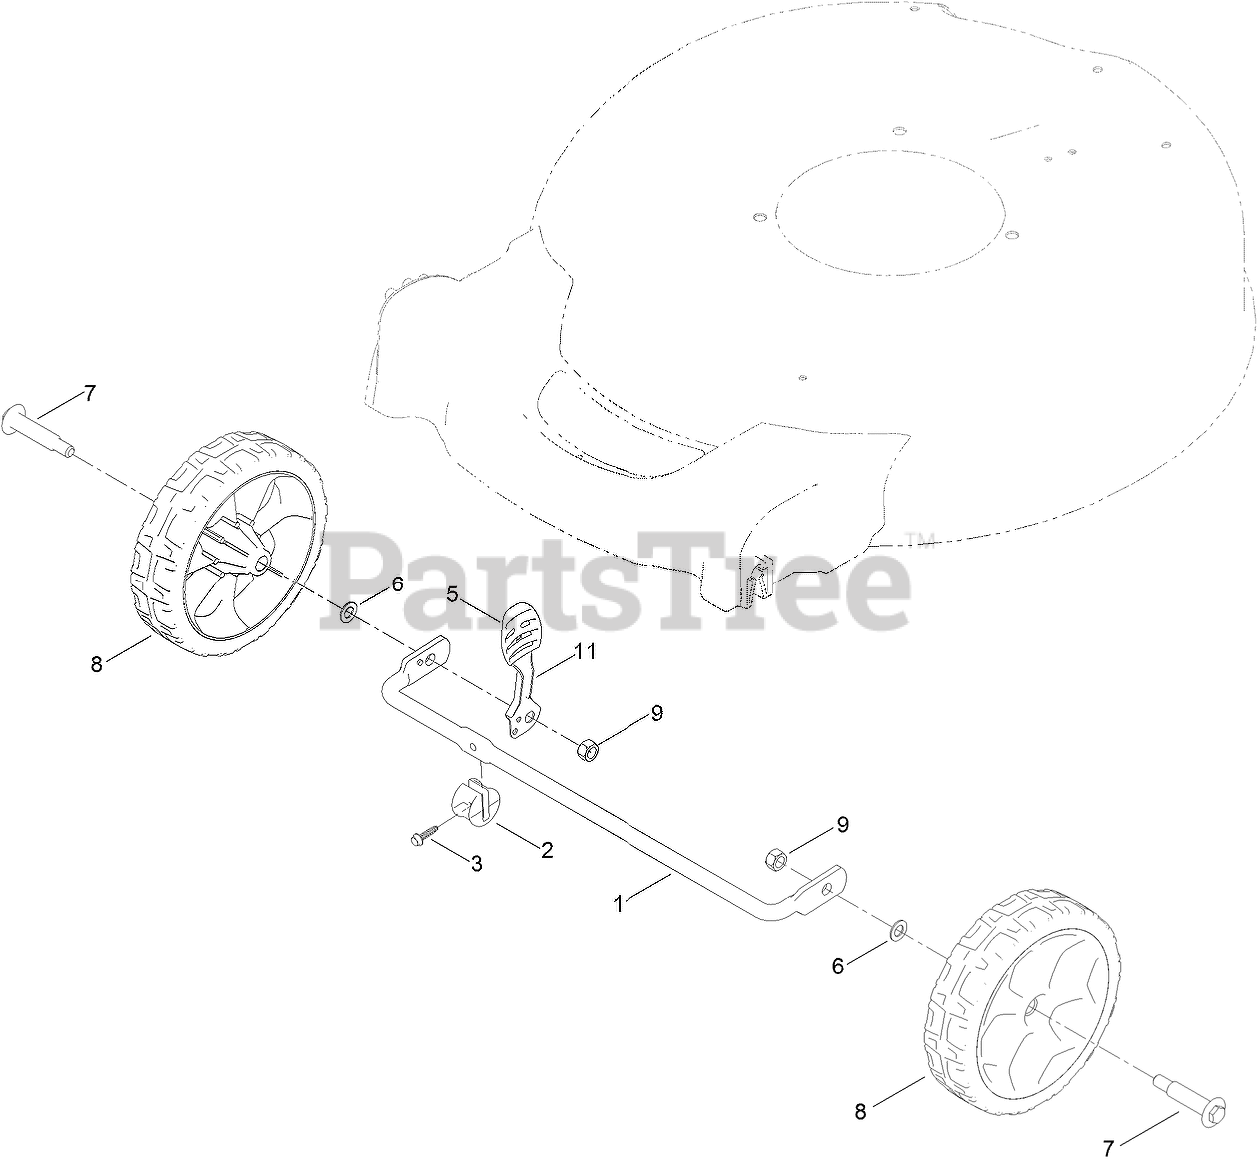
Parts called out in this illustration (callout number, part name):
1	AXLE-FRONT
2	STOP-AXLE
3	SCREW-HWH
5	KNOB-LEVER, HOC
6	WASHER
7	BOLT-SHOULDER
8	7 INCH WHEEL ASM
9	LOCKNUT
11	ARM-SPRING
